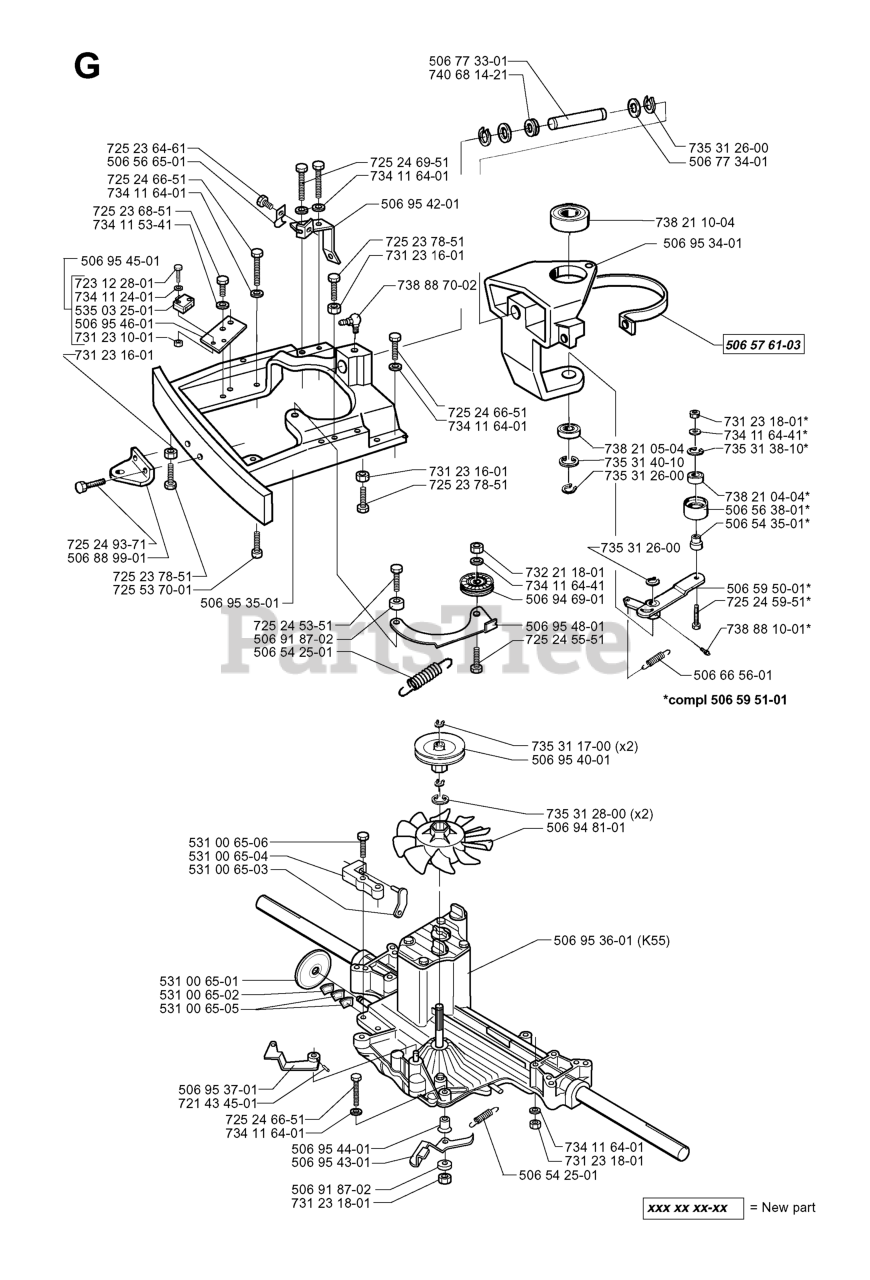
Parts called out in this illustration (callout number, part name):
2	MUFFLER VGT CYLINDER
5	ELBOW
7	MUFFLER ASSEMBLY GUARD
8	RP.IDLER GROOVED
9	KEEPER ASM. BELT ENGINE VGT 96
11	CLUTCH ELECTRIC
12	PULLEY ENG VGT ELECT CLUTCH
15	FUEL TANK 3.5G
16	PAD IDLER TI
17	PAD-SPACER LT
18	FUEL CAP
20	THROTTLE CONTROL
21	SCREW LT
22	CHOKE CONTROL
23	WASHER
24	LOCKWASHER
25	Nut Keps 3/8 - 24 UNF
26	BUSHING OUTLET T
27	STEM FUEL TANK
28	HOSE
29	SPARK ARRESTOR
30	FOAM-STRIP LT
33	NUT
37	HOSE CLAMP
38	BOLT
39	SCREW TT 3/8-16X2-1/4 UNC
40	Screw TT 3/8-16 x 4 unc
42	LOCKWASHER
43	BOLT HEX
45	NUT FLANGE 1/4-20 STARTER NUT
46	WASHER
47	SPACER.ENGINE.CV22.ROUND.PM
48	Washer 13/32 x 1-1/4 x 7 Ga.
51	PIPE CROSSOVER
55	NIPPLE, PIPE 3/8NPT X 4-1/2
56	NIPPLE, PIPE 3/8 NPTX1.00
63	SHIELD, HEAT VGT YP/HUSQ
